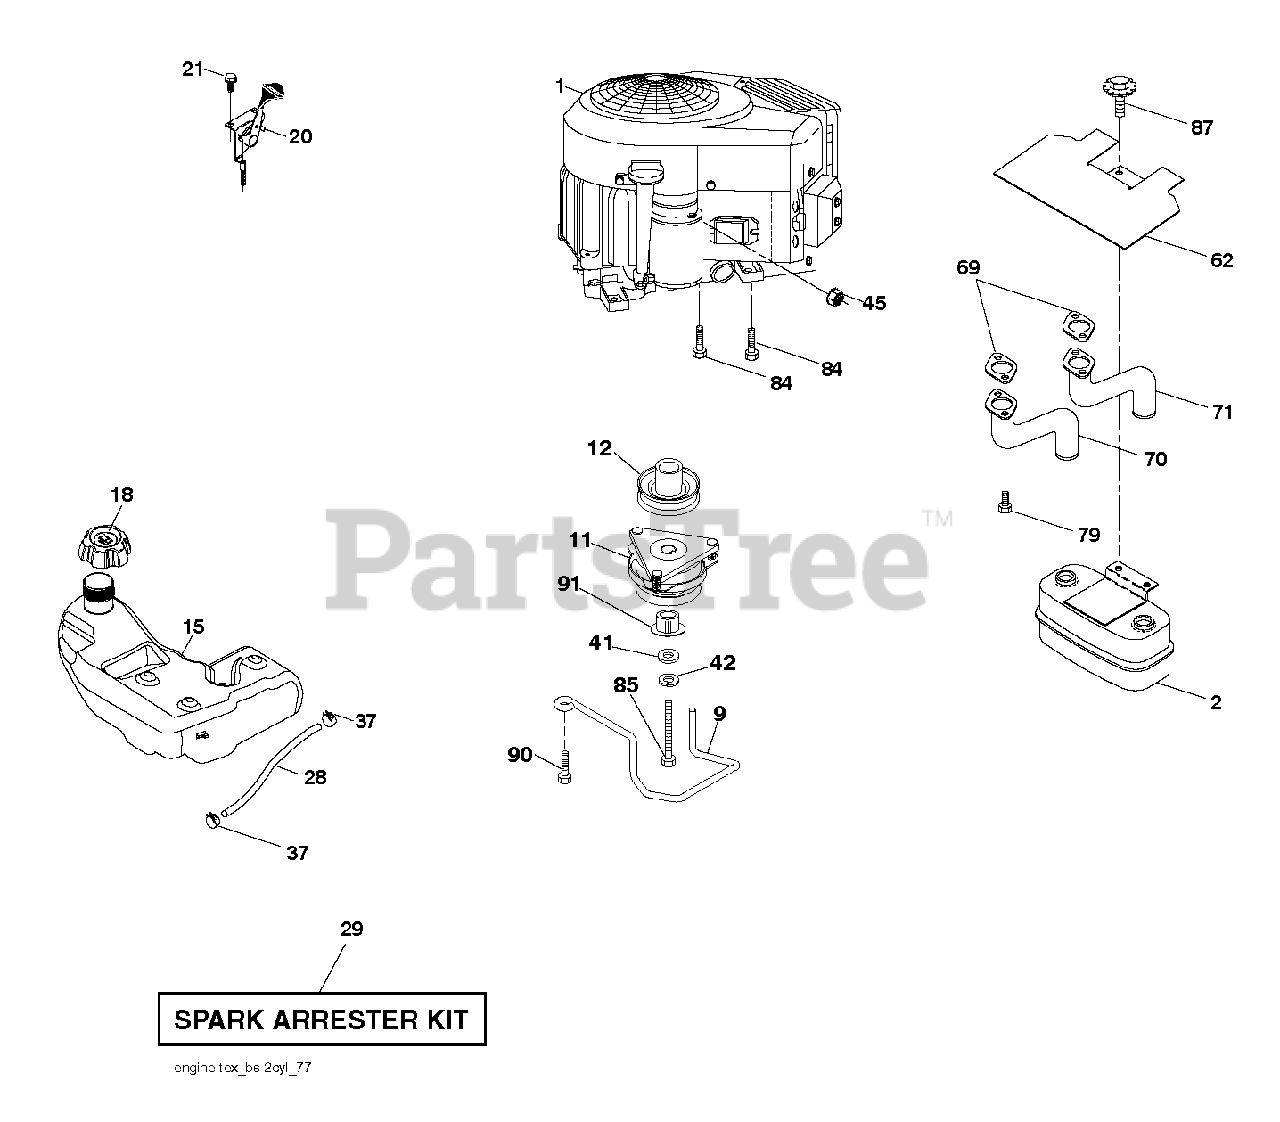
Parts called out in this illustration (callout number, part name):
2	MUFFLER.TWIN.CYL.LOW.TONE
9	KEEPER.BELT.ENGINE.4.2
11	CLUTCH.ELECTRIC.LT.48"*
12	PULLEY.ENGINE.TUFFTORQ
15	TANK.ASSY.3.GAL.EPA
18	CAP ASM.FL.RTCHT.3"GRY.E10
20	CONTROL.TH/CK.COBRA.B&S.TWN.
21	SCREW.#10 X 0.750.BOS (2 2)
28	LINE.FUEL.64"REAR.EMIS
29	KIT.SPARK ARRESTOR(392390 B&S)
37	HOSE CLAMP
42	LOCKWASHER
45	NUT
62	SHIELD.HEAT.MUFFLER
69	GASKET.MUFFLER
70	RP.EXHAUST.TUBE.LH.BS/TWIN
71	RP.EXHAUST.TUBE.RH.BS/TWIN
79	SCREW.SOCKET.HEAD.5/16-18
84	SCREW.3/8-16
85	BOLT HEX 7/16-20X4-1/4"
87	BOLT, 5/16-18 X 1 3/4
90	SCREW 3/8-16X1
91	BUSHING.1.375OD
